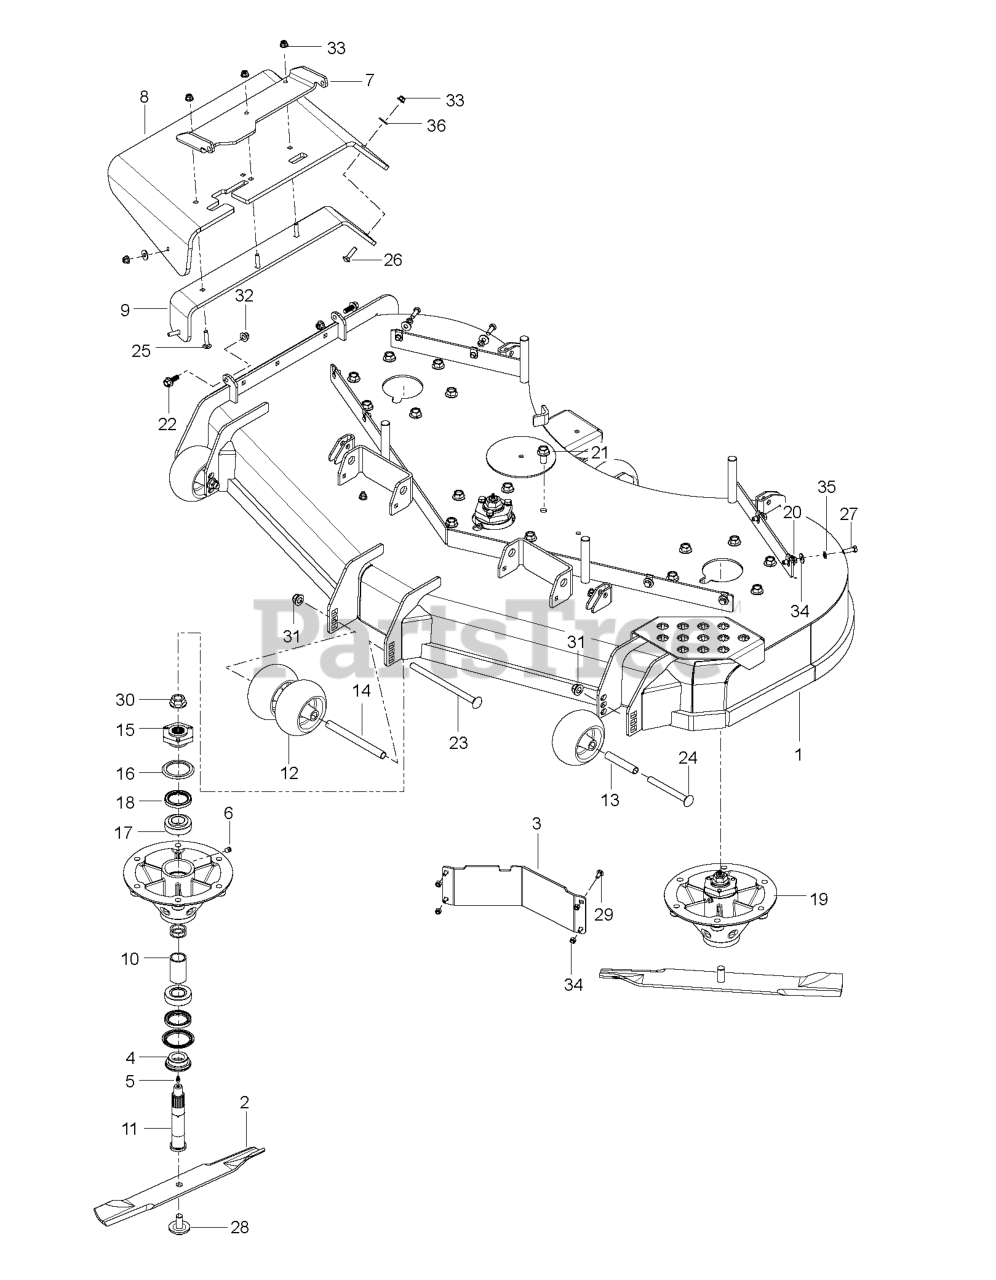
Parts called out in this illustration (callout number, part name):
1	RedMax TBD
2	BLADE OEM - 25"
3	BAFFLE, DIVERTER 72" BLACK
5	ZERK
6	PLUG-VENTED
7	BRKT - CHUTE MTG BLACK
8	CHUTE, DISCHARGE 60-72
9	BRKT - CHUTE SUPPORT BLACK
12	ROLLER, GAUGE .635 BORN
13	TUBE, ROLLER AXLE
14	TUBE, ROLLER AXLE LONG
16	SEAL V-RING 55MM
17	BEARING
18	SEAL SHAFT
19	SPINDLE.ASSY.IRON
20	U-CLIP 5/16-18 NUT RETAINER
21	HHFS 1/2-13 X 1 GR5 ZD
22	HHFS 3/8-16 X 1 GRD 5 ZD
23	RHSNB 1/2-13 X 8 GR5 ZD
24	RHSNB 1/2-13 X 4.75 GR5 ZD
25	RHSNB 5/16-18 X 1-1/2 GR 5 ZD
26	BOLT, CARRIAGE 5/16X1-1/4
27	HCS 5/16C X 1
28	BLADE BOLT/WASHER
29	1/4-20X3/4 CARR BLT
30	NUT FLANGE 3/4-16
31	NUT, 1/2-13 HEX FLG NYLOC ZD
32	NUT 3/8-16 HEX FLG NYLOC ZD
33	5/16-18 NYLOC FLANGE NUT
34	RP_NUT 1/4-20 NYLOC
35	WASHER 5/16 LOCK
36	WASHER
